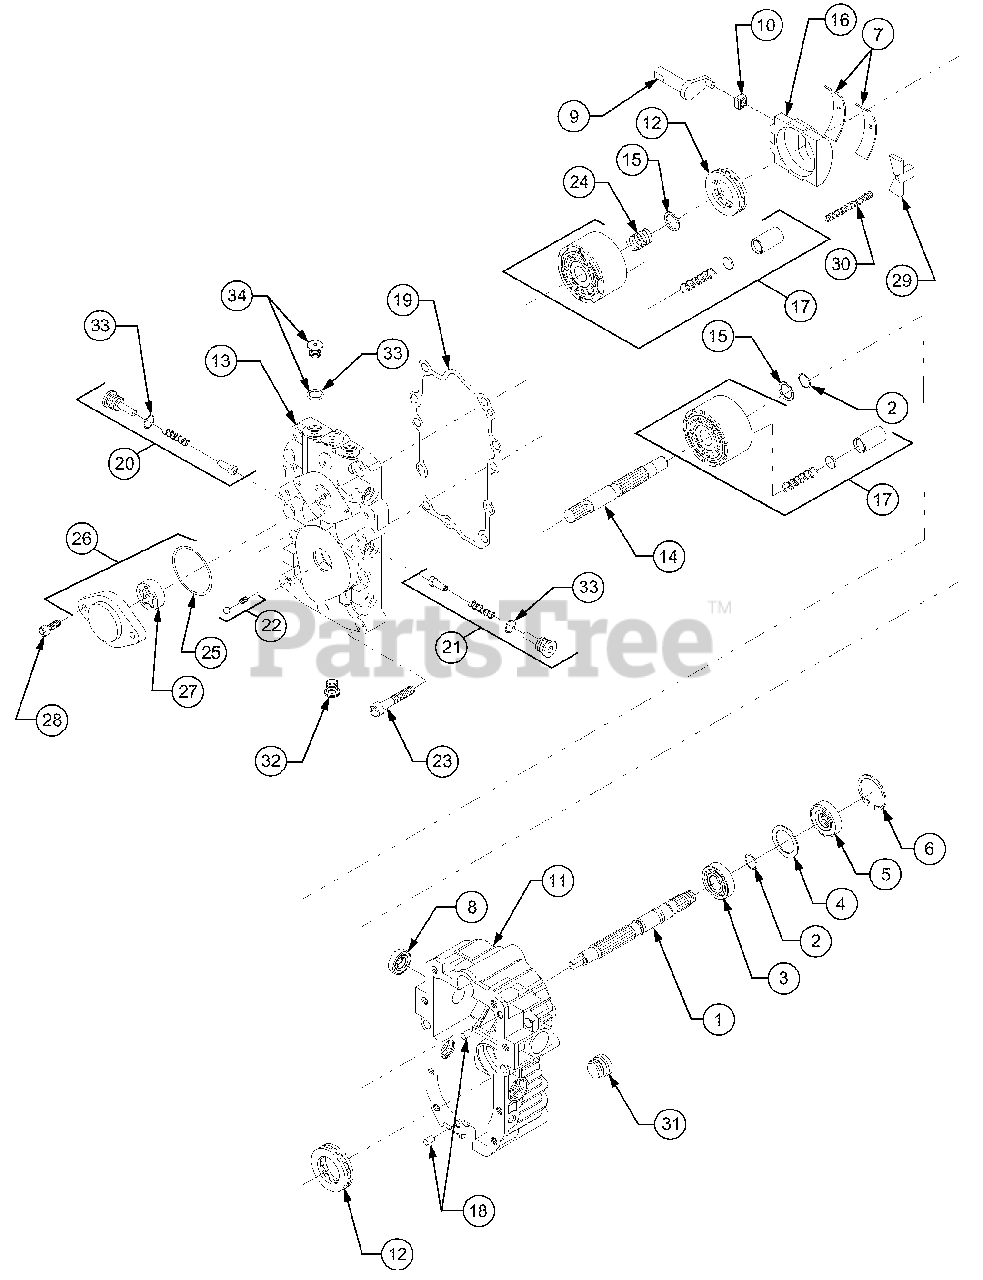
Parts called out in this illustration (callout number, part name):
1	Shaft, Pump (Splined)
2	Ring, Retaining
3	Bearing, Ball
6	Ring, Retaining
7	Bearing, Cradle
9	Arm, Trunnion
10	Guide, Slot
11	Housing Kit
12	Bearing Assembly, Thrust Ball
13	Center Section Kit
14	Shaft, Motor
15	Washer, Block Thrust
16	Swash Plate
17	Block Assembly
19	Gasket, Center Section
20	Kit, Check Valve
21	Kit, Orificed Check Valve
22	Kit, Charge Relief Valve
23	Screw, Socket Hd
24	Spring, Block
26	Kit, Charge Pump
27	Gerotor Assy
28	Screw, Socket Hd
30	Spring, Compression
